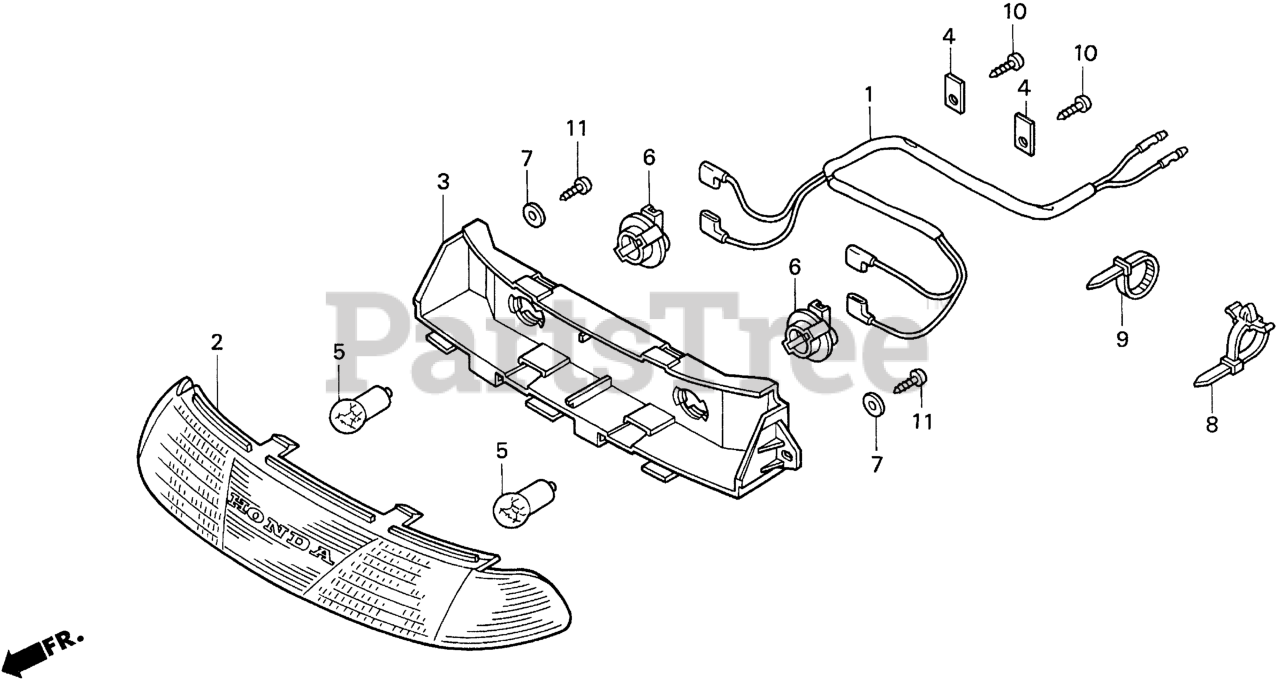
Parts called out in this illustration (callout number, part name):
1	SUB-HARNESS, HEADLIGHT
2	LENS, HEADLIGHT
3	REFLECTOR, HEADLIGHT
4	PLATE, SUB-HARNESS
5	BULB (12VX17W)
6	SOCKET ASSY., HEADLIGHT
7	WASHER, STOPPER
8	BAND, WIRE HARNESS (150MM) (NATURAL) DUAL QTY = (2) (SINGLE)
9	BAND, WIRE
10	SCREW, TAPPING (5X16)
11	SCREW, TAPPING (5X20) (PO)
